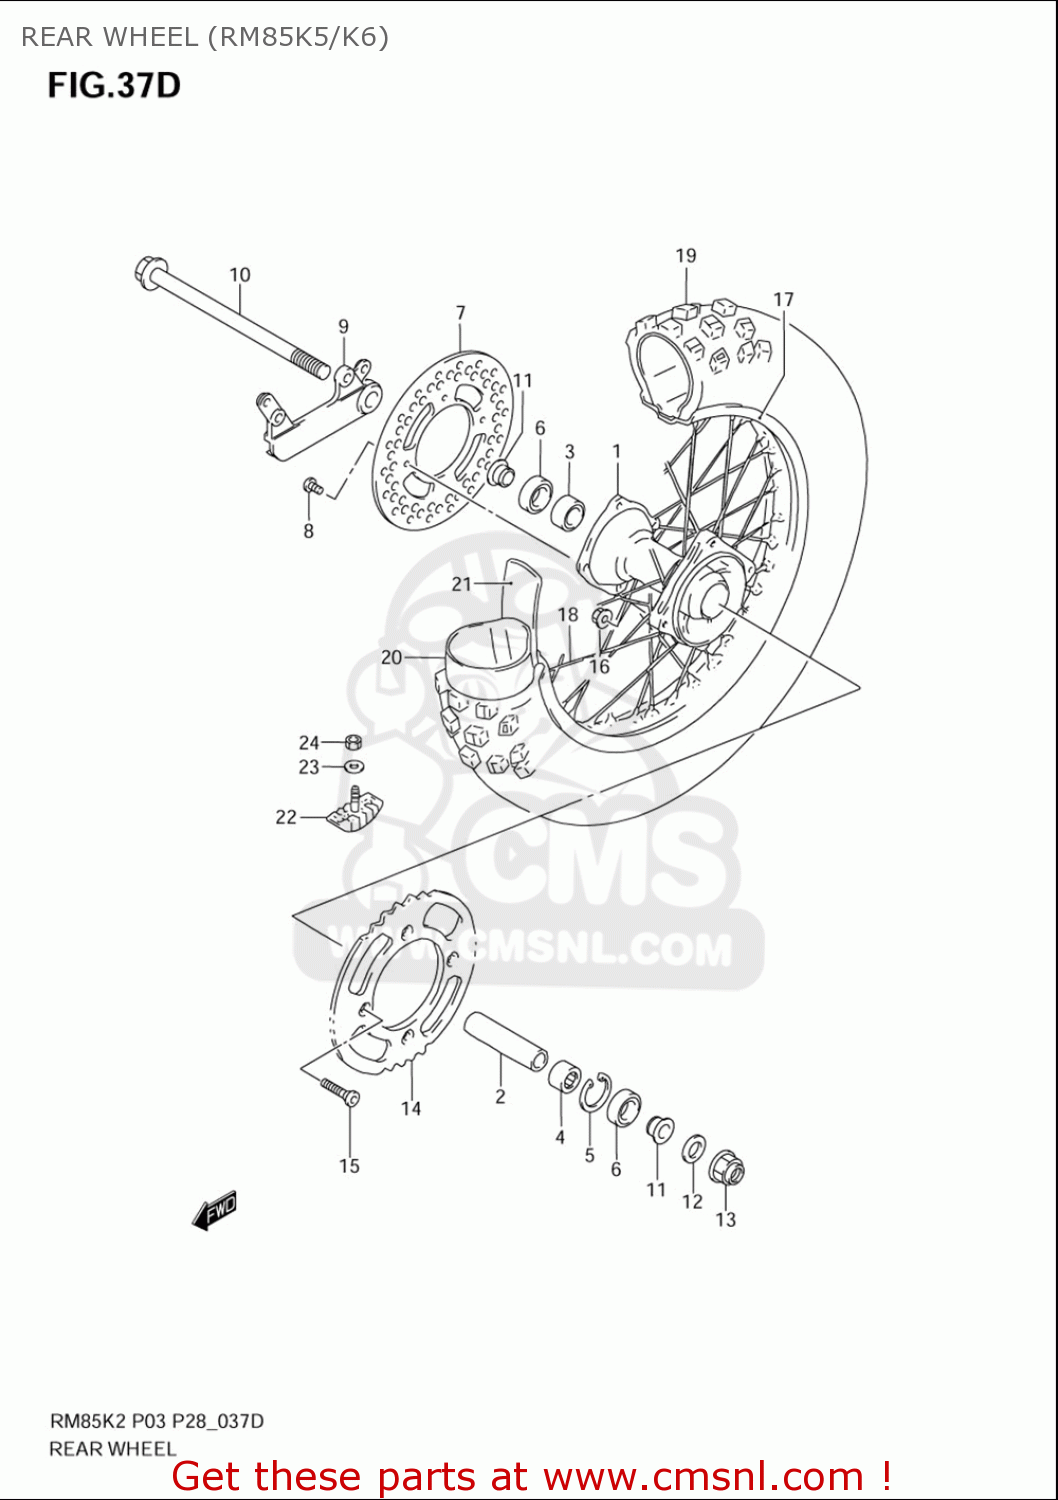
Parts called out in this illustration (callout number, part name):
1	HUB,RR WHEEL
2	SPACER,RR HUB BEARING
3	BEARING
4	BEARING(15X35X11)
5	CIRCLIP
6	SEAL,OIL(20X35X7)
7	DISC,RR BRAKE
8	SCREW
9	BRACKET,RR CALIPER
10	AXLE,RR
11	SPACER,RR AXLE
12	WASHER
13	NUT
14	SPROCKET,RR(47T)
15	BOLT(8X30.5)
16	NUT
17	RIM,RR WHEEL(1.60X14 AL)
18	SPOKE SET,RR WHEEL
19	TIRE,RR(90/100 14)
20	TUBE ASSY,WHEEL INNER
21	PROTECTOR,WHL INR TUBE
22	STOPPER,BEAD(1.85)
23	WASHER
24	NUT
